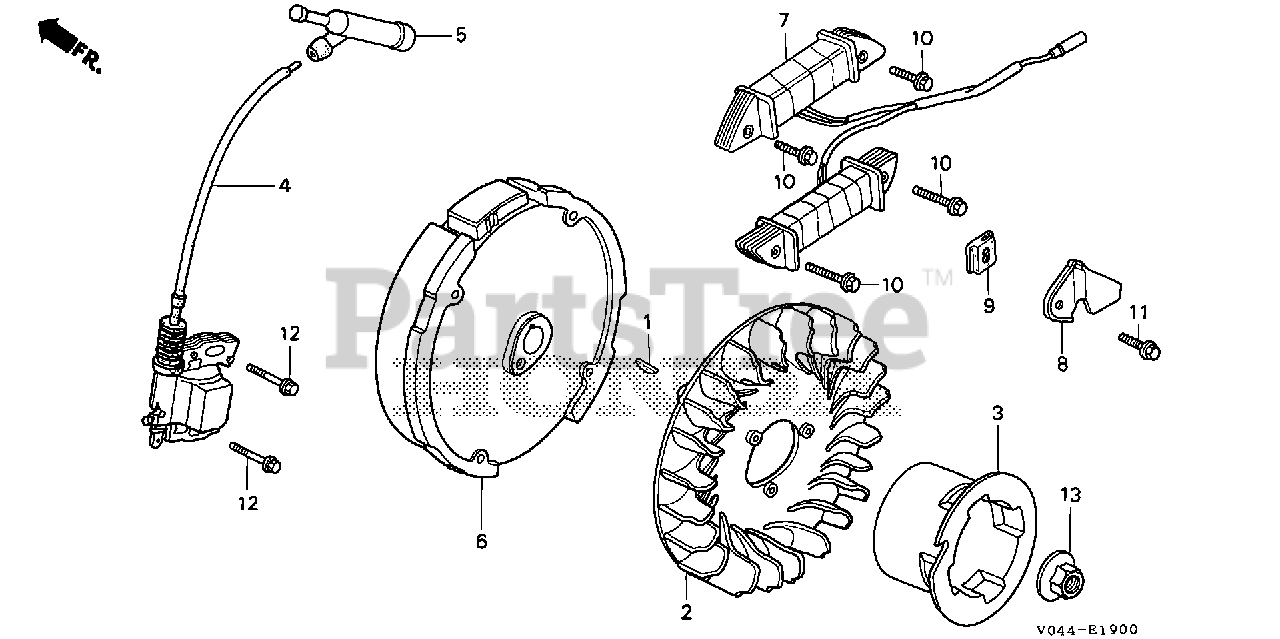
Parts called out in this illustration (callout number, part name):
1	KEY, SPECIAL WOODRUFF (25X18)
2	FAN, COOLING
3	PULLEY, STARTER
4	COIL ASSY., IGNITION Use up to Engine SN 1530314.
5	CAP ASSY., NOISE SUPPRESSOR (Honda Code 3526837). (NICHIWA Y-EZ RTFM256)
6	FLYWHEEL (LAMP)
7	COIL ASSY., LAMP (12V/50W)
8	CLAMP, WIRE
9	GROMMET, WIRE
10	BOLT, FLANGE (6X28) (CT200) Use up to Engine SN 1530314.
11	BOLT, FLANGE (5X10)
12	BOLT, FLANGE (6X25) Use up to Engine SN 2056819.
13	NUT, SPECIAL (14MM)
